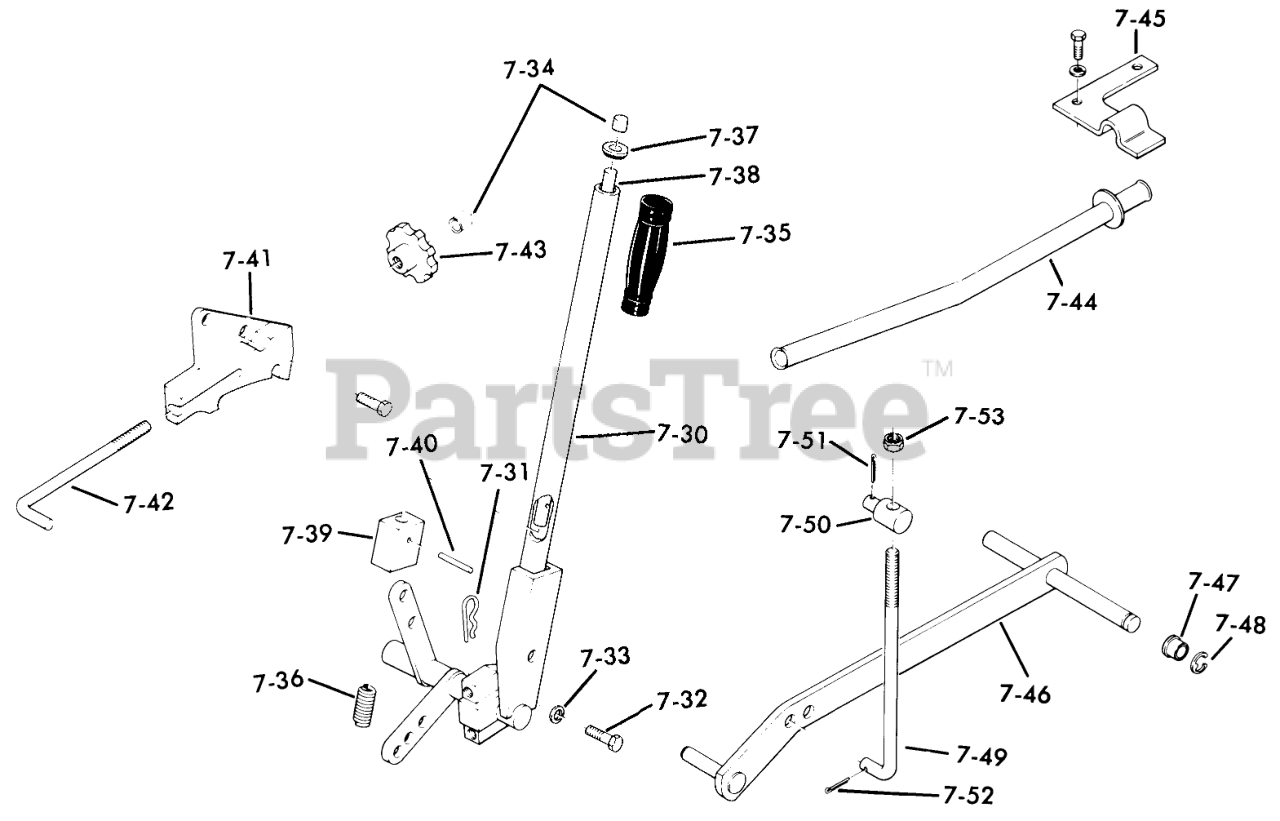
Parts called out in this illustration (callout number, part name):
7-30	Lift Lever
7-31	Hairpin
7-32	H H C S
7-33	Lockwasher
7-34	CAP-ROD, PLUNGER
7-35	HANDGRIP
7-36	SPRING-COMPRESSION
7-37	Guide-Rod
7-38	PLUNGER ROD
7-39	LOWER PLUNGER R
7-40	Roll Pin
7-41	Quadrant
7-42	ROD-LIFT CONTROL
7-43	KNOB-LIFT CONTROL
7-44	TUBE ASSY COMPLET R
7-45	Clamp-Tube
7-46	ASSY LIFT BAR R
7-47	BUSHING
7-48	E Ring
7-49	ROD-LIFT
7-50	TRUNNION-LIFT
7-51	Hairpin
7-52	Cotter Pin
7-53	NUT
